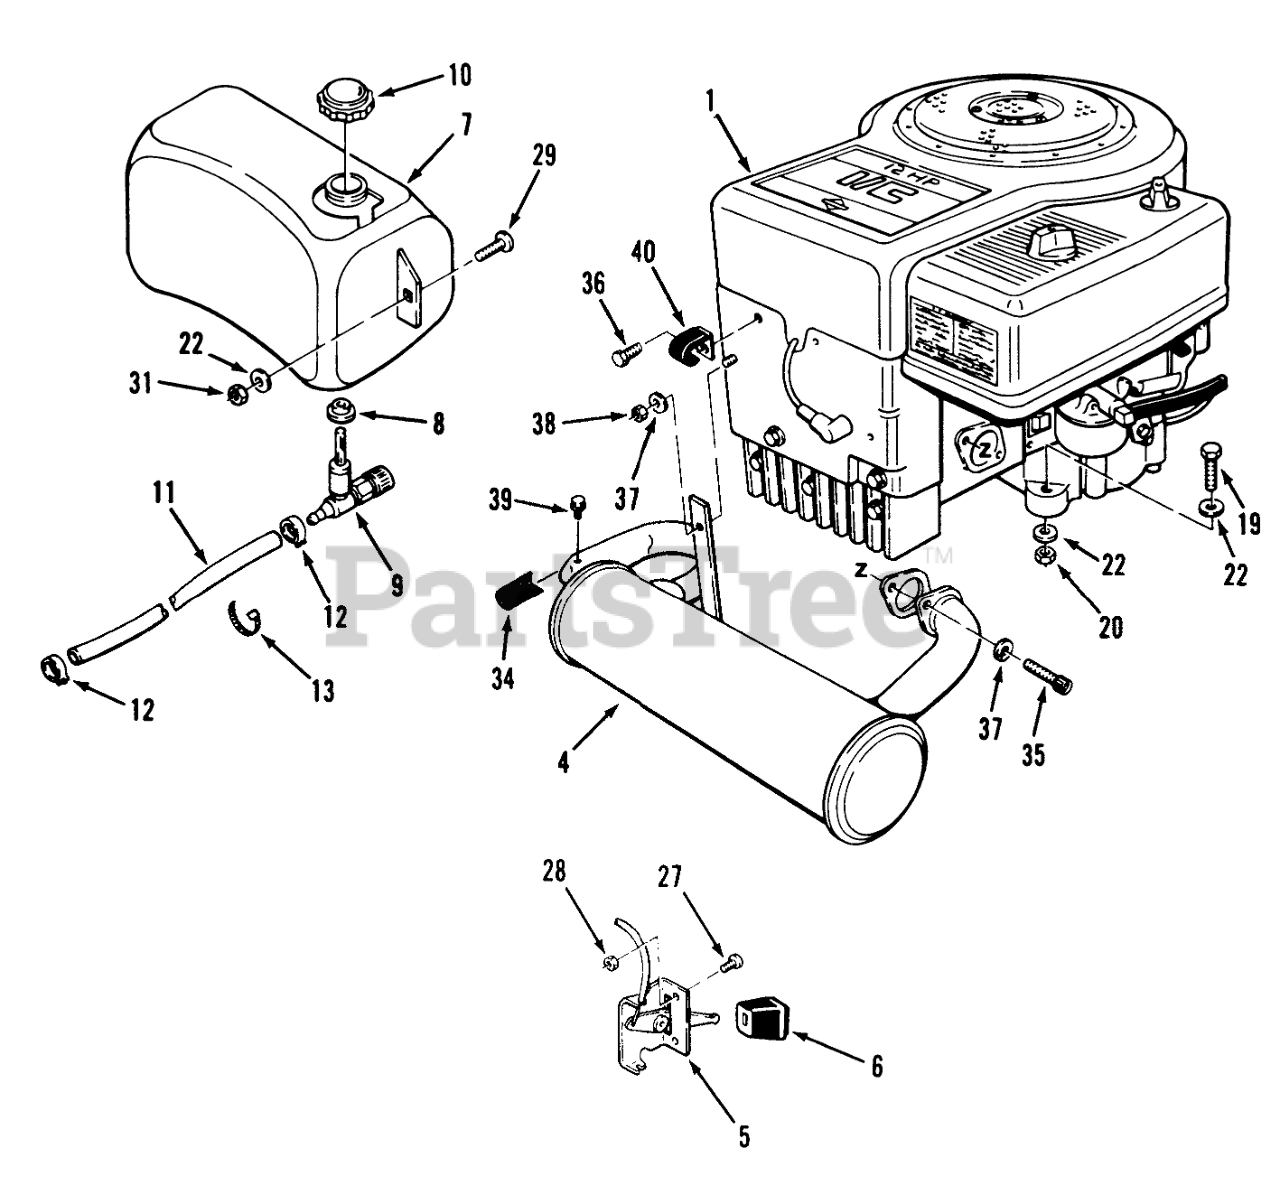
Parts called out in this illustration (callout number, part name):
1	Engine-12HP-B & S Model 281707-0226-01 Model 212-HA
4	MUFFLER-EXHAUST
5	THROTTLE-CONTROL
6	KNOB-CONTROL
7	Fuel Tank Assembly (Incl. Ref. #8 & 9)
8	BUSHING
9	VALVE-FUEL
10	CAP GAS
11	FUEL LINE 19" OF 6554
12	CLAMP-HOSE
13	PLASTIC TIE
19	HHCS
20	Nut
22	WASHER-PLAIN
27	Screw
28	Nut
29	BOLT-CARR
31	NUT-LOCK, NI
35	SHCS 5/16-18X.625
36	SCREW-HH
37	WASHER-LOCK
38	Nut-Hex
39	BOLT-HEX S.T. #8X1/2
40	J-CLIP
